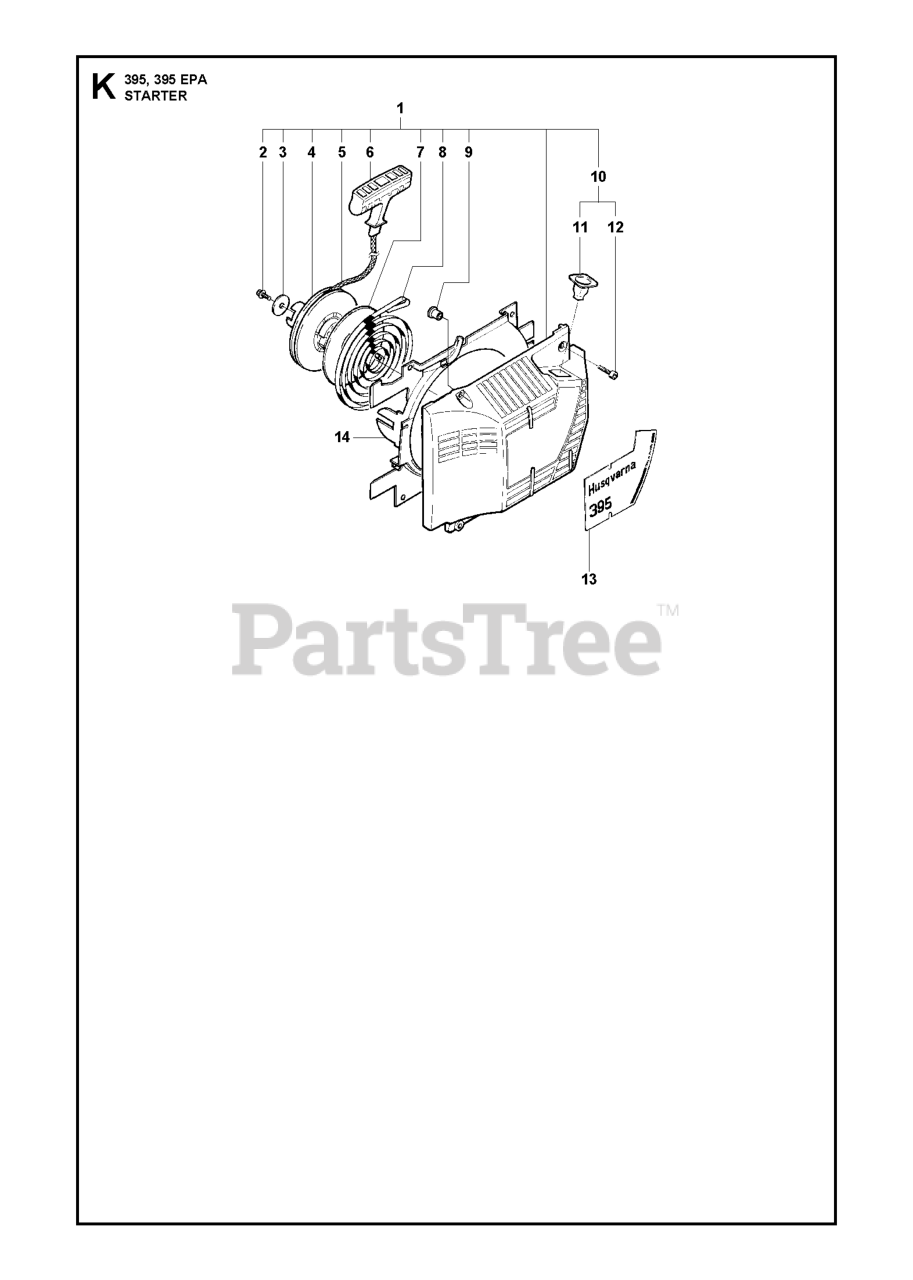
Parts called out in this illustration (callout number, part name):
1	STARTER HOUSING ASSY.
2	SCREW IHSCFT PW5.5X16 8.8 ZN/
5	STARTER ROPE
6	STARTER HANDLE
8	RECOIL SPRING
10	STARTER HOUSING
12	SCREW.CCRPANMO.M5X19 10.9 TBO
13	STARTING DECAL
14	AIR CONDUCTOR
